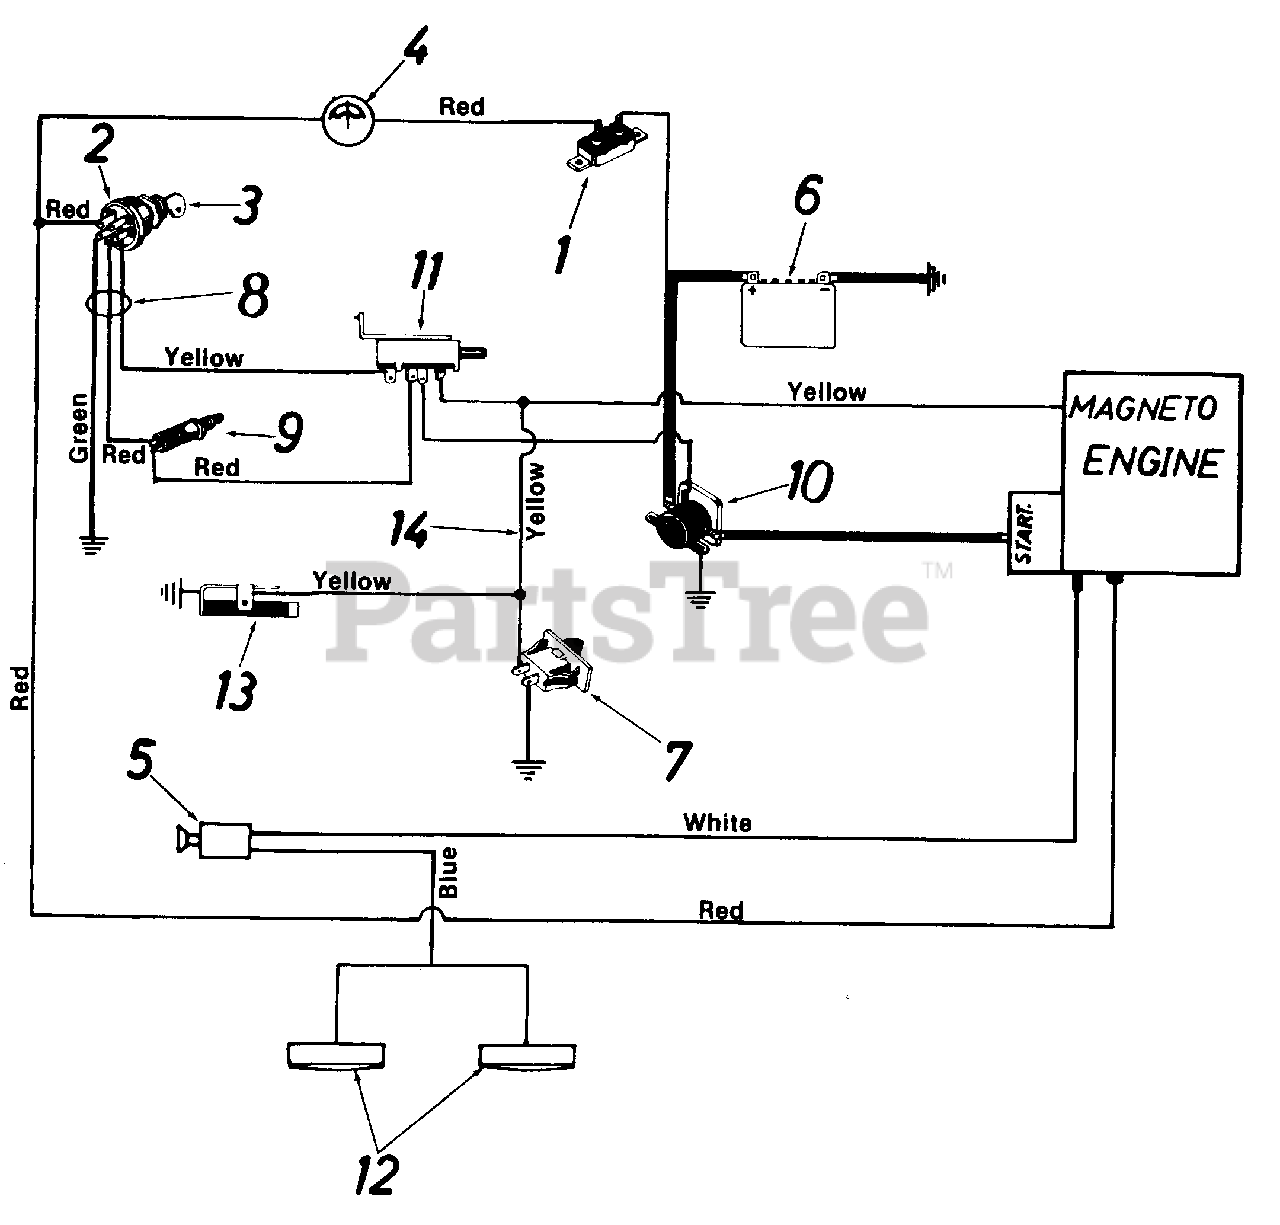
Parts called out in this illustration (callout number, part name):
1	Circuit Breaker
2	Ignition Switch
3	Ignition Key
4	Ammeter
5	Headlight Switch
6	Battery
7	Safety Switch
8	Wiring Harness
9	Safety Switch
10	Solenoid
11	Safety Switch
12	Headlight
13	Spring Switch
14	Wire Lead
